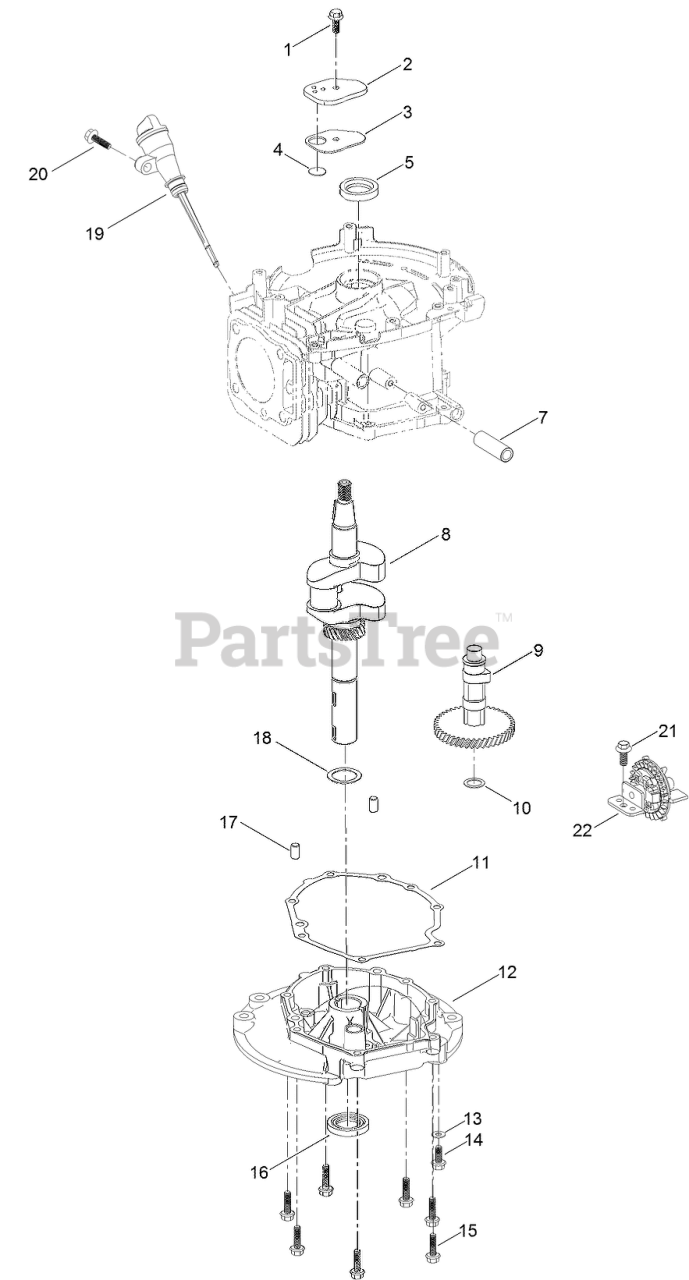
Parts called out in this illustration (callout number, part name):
1	SCREW-HHF
2	COVER-BREATHER
3	GASKET-COVER, BREATHER
4	VALVE-BREATHER
5	SEAL-OIL
7	TUBE-BREATHER
8	CRANKSHAFT ASM
9	CAMSHAFT ASM
10	WASHER-FLAT
11	GASKET-COVER, CASE
12	COVER-CRANKCASE
13	WASHER-PLAIN
14	SCREW-HHF
15	SCREW-HHF
16	SEAL-OIL
17	PIN-DOWEL
18	WASHER-FLAT
19	DIPSTICK AND FILL TUBE KIT
20	BOLT-FLANGE
21	SCREW-HWH, THD FORM
22	GOVERNOR GEAR ASM
